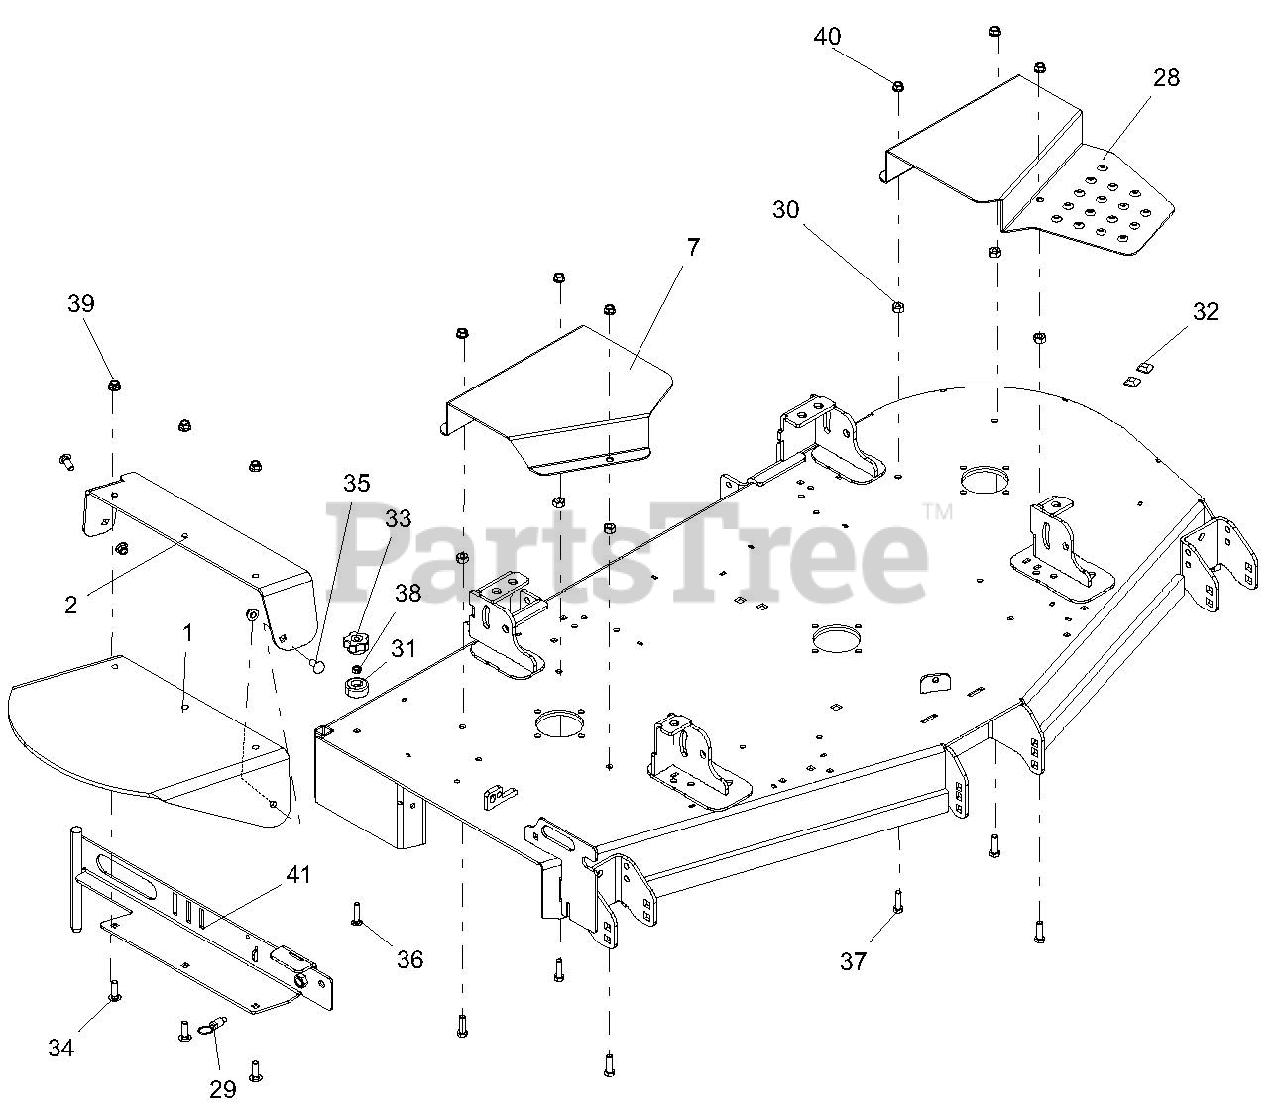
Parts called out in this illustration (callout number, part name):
1	CHUTE, RUBBER DISCHARGE
2	SUPPORT, RUBBER DISCH CHUTE
7	GUARD, 60"-66" RH DECK BELT
7	GUARD, 52" RH DECK BELT
7	GUARD, 72" RH DECK BELT
28	GUARD, 60" LH DECK BELT-W/STEP
28	GUARD, 66" LH DECK BELT-W/STEP
28	GUARD, 52" LH DECK BELT-W/STEP
28	GUARD, 72" LH DECK BELT-W/STEP
29	PULL PIN,.50-13THDX.310 PLNGR
30	NUT-HEAVY HEX .38-16
31	BUMPER, RECESSED 1.50 X .63 W/.31 HOLE
33	KNOB, CLAMPING
34	BLT-RDHDSQNK .38-16X1.25 G5 YWZC
35	BLT-RDHDSQNK .38-16X1.00 G5 YWZC
36	BLT-RDHDSQNK .31-18X1.50 G5 YWZC
37	BLT-HEX .38-16X1.25 GR5 YWZC
38	NUT-LK-CTR .31-18 YWZC
39	NUT-LK-NYL-FLG .38-16 YWZC
40	NUT-SPNLK-FLG .375-16 YWZC
41	WLDMT, 52"-60" DISCH CHUTE MTG
41	WLDMT, 66"-72" DISCH CHUTE MTG
